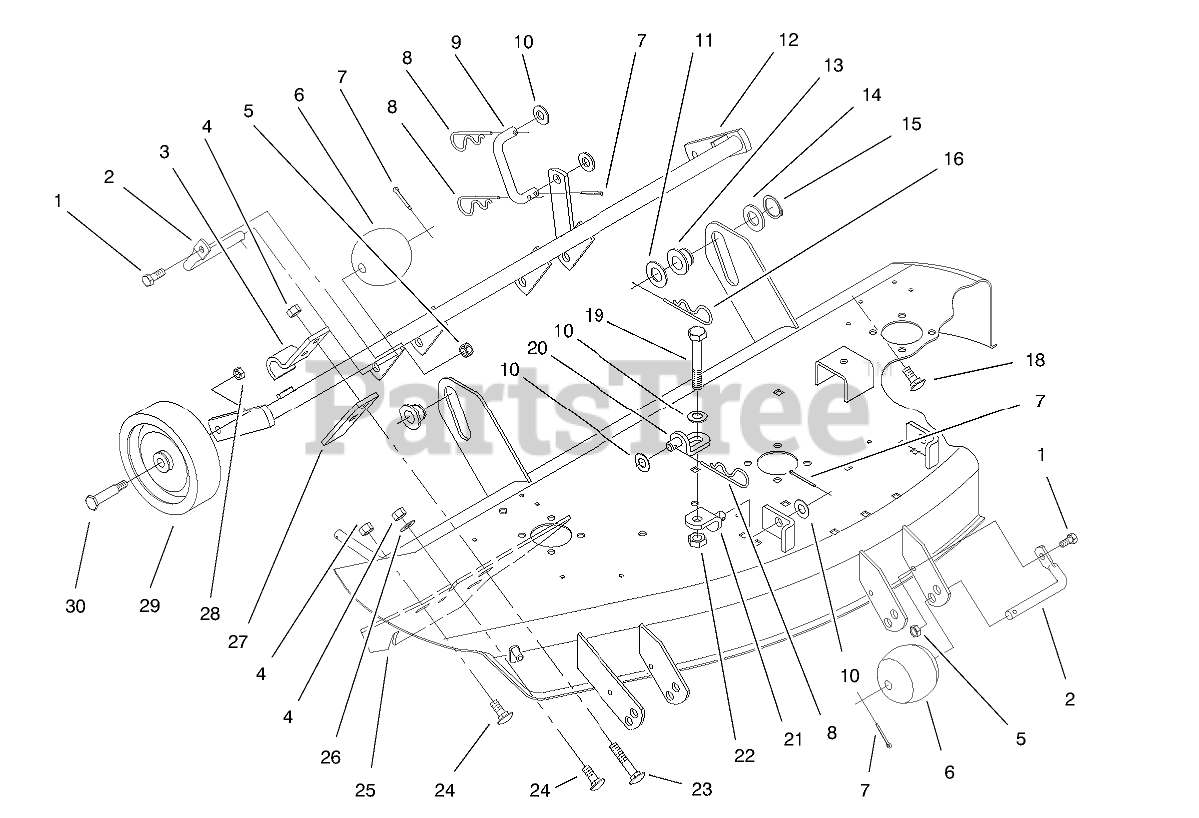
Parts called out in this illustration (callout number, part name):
1	SCREW-HH
2	SHAFT-ROLLER
3	Clamp
4	NUT-LOCK, NI
5	NUT-LOCK, NI
6	ROLLER
7	PIN-COTTER
8	PIN-COTTER, HAIR
9	LINK-REAR
10	WASHER-FLAT
11	WASHER-FLAT
12	Support-Gage Wheel
13	ROLLER-LIFT
14	WASHER
15	RING-RETAINING
16	PIN-HAIR
18	SCREW-CARR
19	SCREW-HH
20	BRACKET-LIFT, LOWER
21	BRACKET-LIFT, UPPER
22	NUT-JAM
23	SCREW-CARR
24	SCREW-CARR
25	Plate-Wear
26	WASHER-FLAT
27	Bar
28	NUT-HEX
29	WHEEL
30	BOLT-SHOULDER
